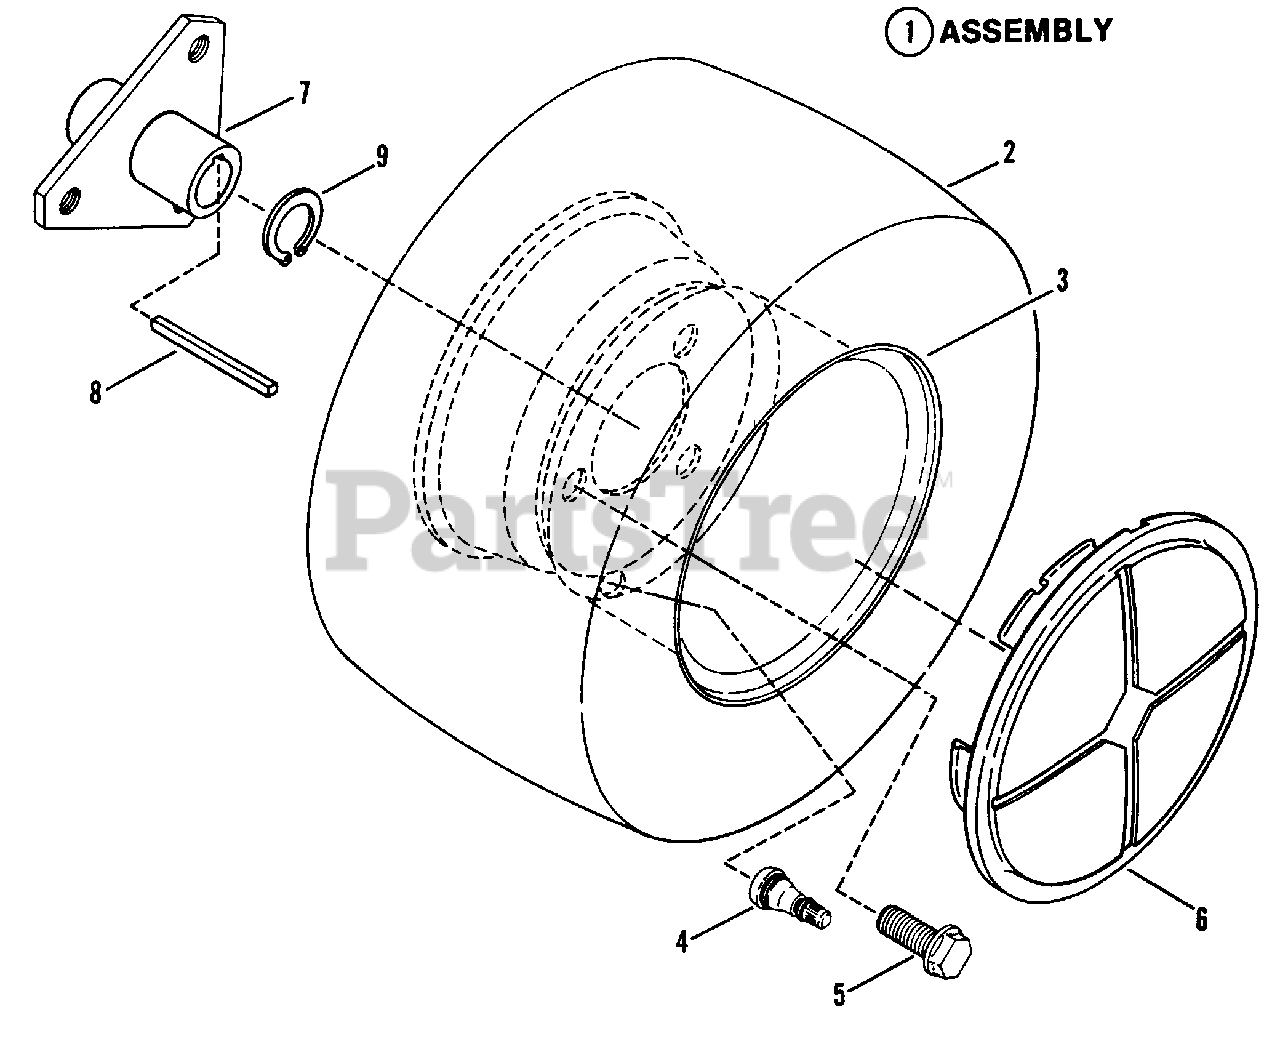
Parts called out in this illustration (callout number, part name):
1	ASSEMBLY, Rear Tire & Rim (41" Deck) (No longer available)
2	TIRE, 18x8.504
3	RIM, 8x7
4	VALVE, Air (Snap-In)
5	BOLT, 1/2-20x3/4" Lug
6	HUB-CAP
7	HUB, Rear Wheel
8	KEY, Square, 3/16x2-1/2"
9	RING, Retaining EXT .75
